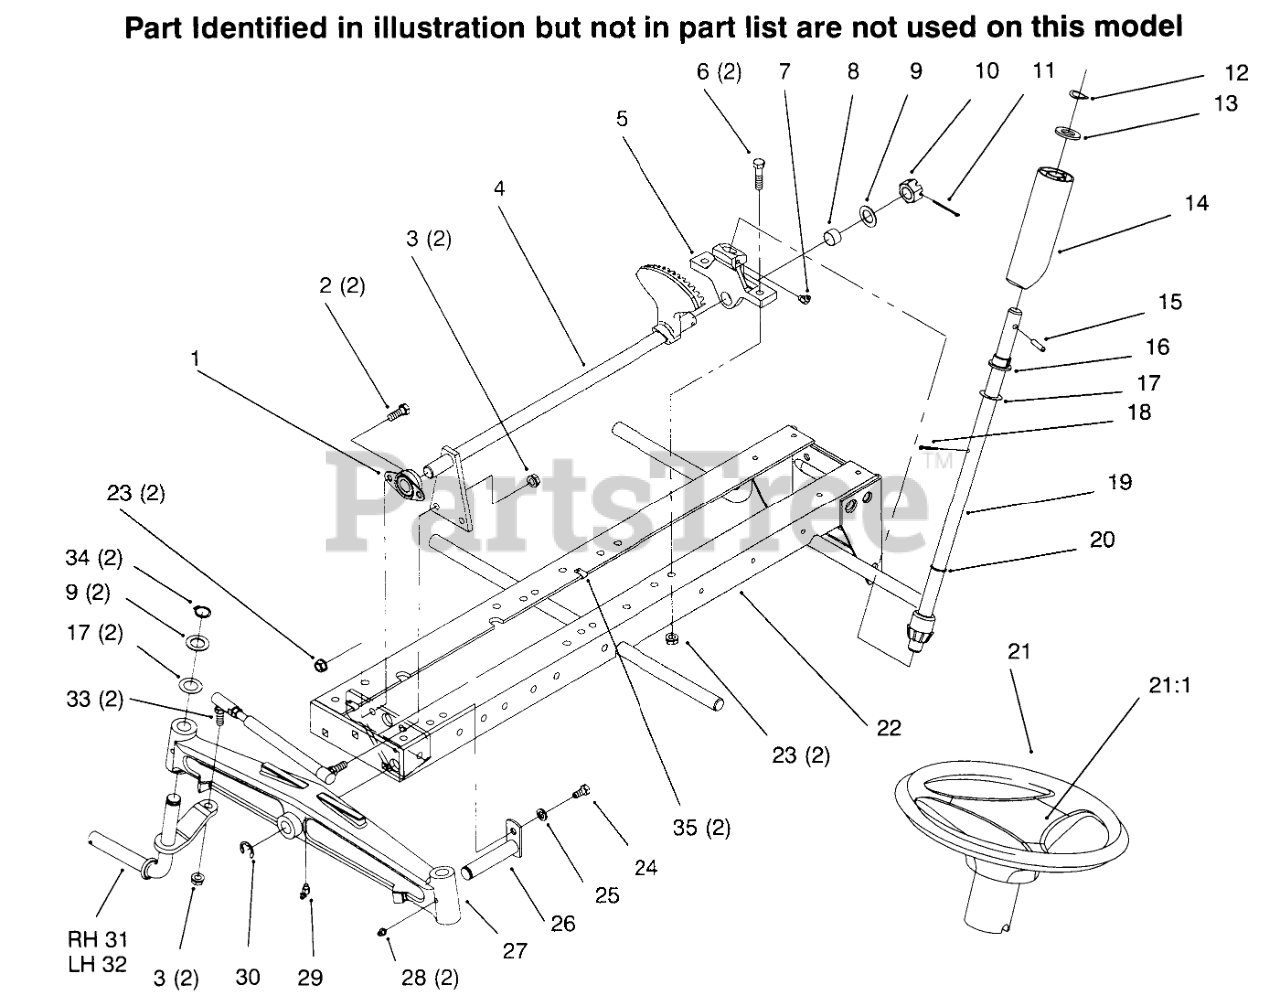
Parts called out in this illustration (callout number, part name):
1	BEARING-FLANGED
2	SCREW-HH
3	NUT-LOCK
4	Shaft
5	Support-Steering
6	SCREW-HH
7	FITTING-GREASE
8	BEARING-BRONZE
9	WASHER
10	NUT-HEX, SLOTTED
11	PIN-COTTER
12	WASHER-BOWED
13	WASHER-FLAT
14	TUBE-STEERING
15	PIN-ROLL
16	BEARING-FLANGED
17	PIN-COTTER
17	WASHER-SHIM
19	STEERING SHAFT ASM
20	O-RING
21	WHEEL - STEERING 15"
21:1	COVER-WHEEL
22	Frame
23	NUT-LOCK, NI
24	SCREW-HH
25	WASHER-LOCK
26	PIN AND PLATE ASM
27	AXLE-FRONT
28	FITTING-GREASE
30	E-RING
31	RH SPINDLE WA
32	LH SPINDLE ASM
33	ASM-Rod
34	RING-RETAINING
35	CLIP-WIRE
